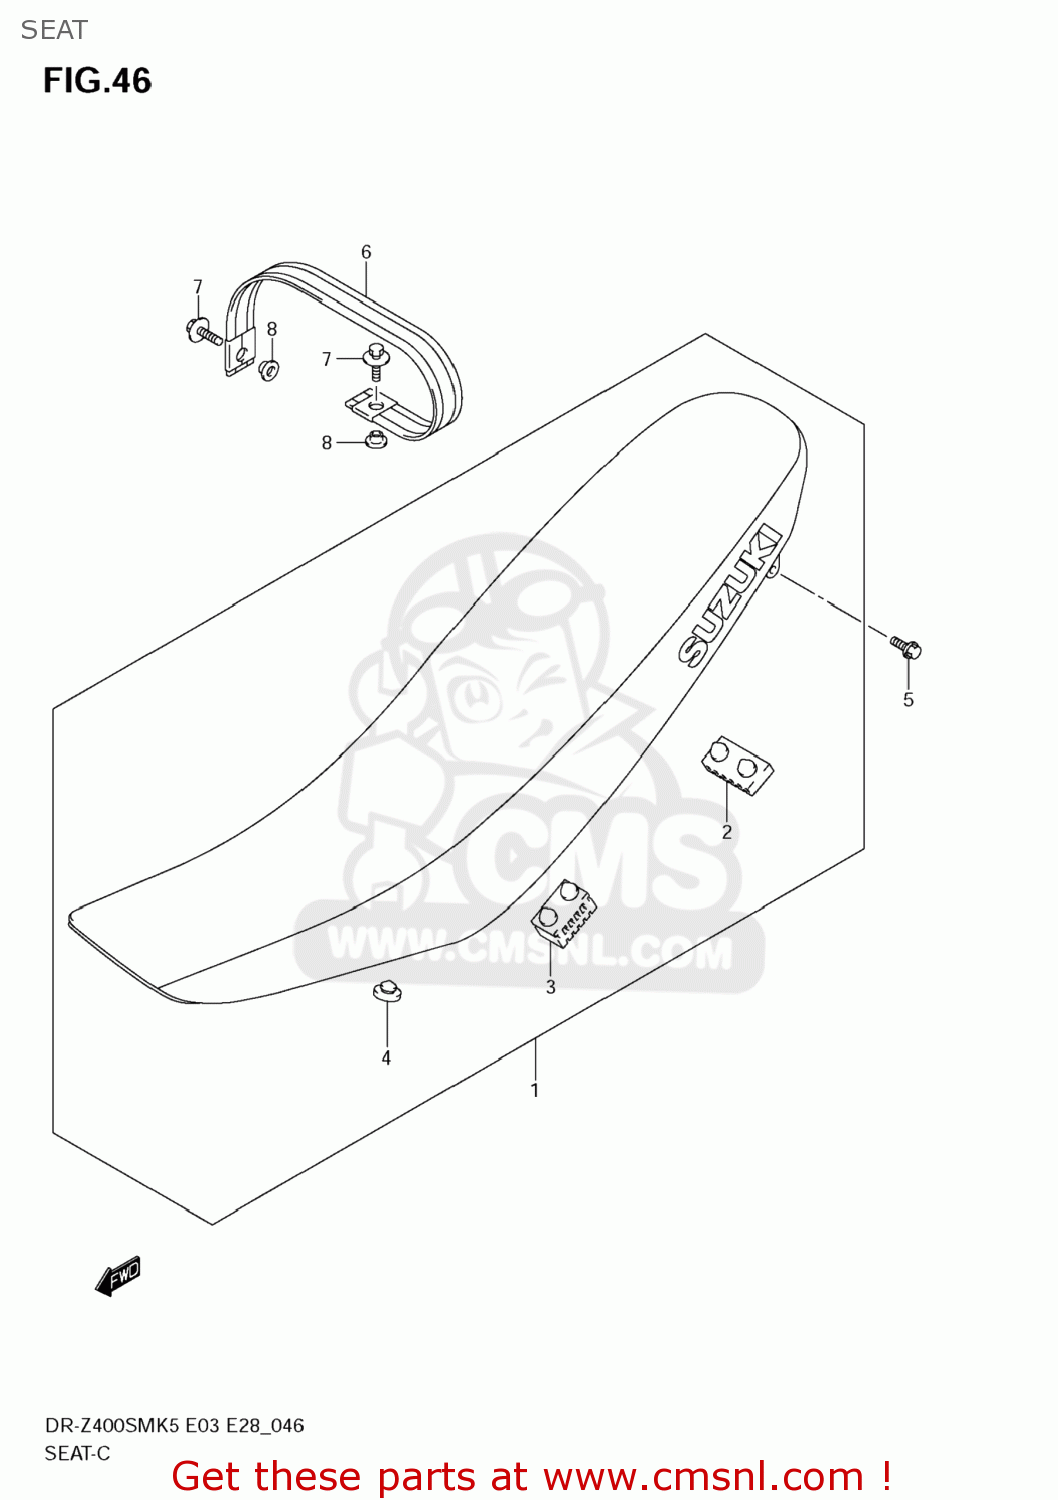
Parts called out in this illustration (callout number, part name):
1	SEAT ASSY
2	CUSHION,SEAT(40X20X6)
3	CUSHION,SEAT(40X20X15)
4	CUSHION
5	BOLT(6X20)
6	BAND ASSY,SEAT
7	BOLT(6X25)
8	WASHER
